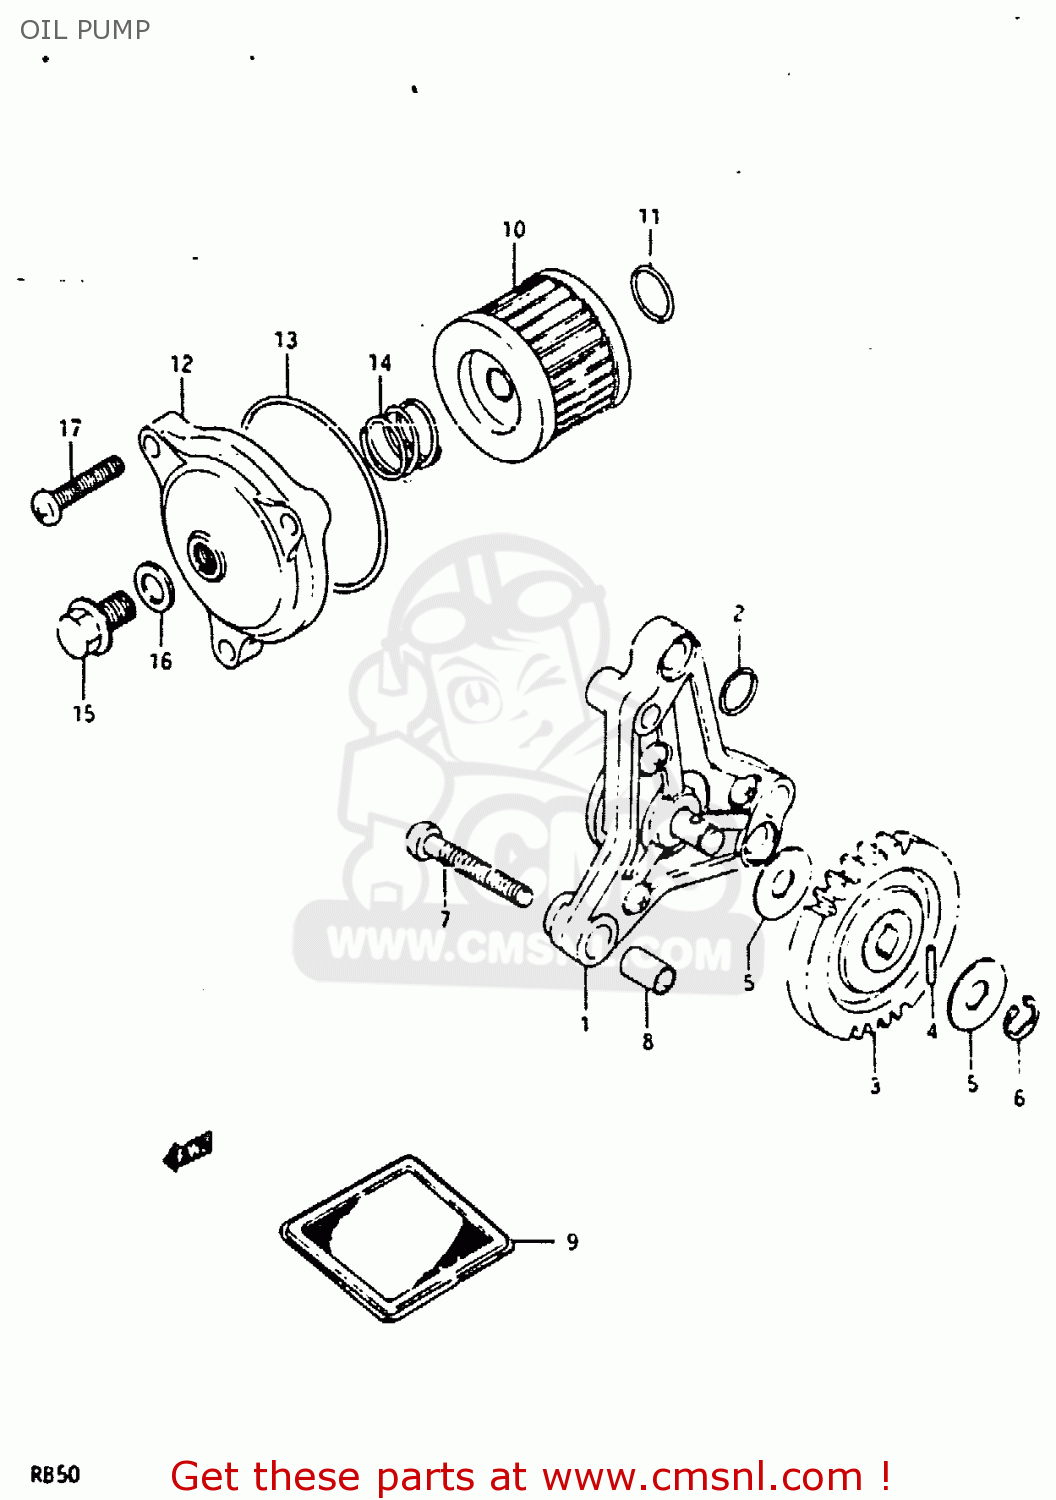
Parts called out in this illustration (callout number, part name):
1	PUMP ASSY,ENGINE OIL
2	O-RING
3	GEAR,OIL PUMP DRIVEN (N
4	PIN(2.5X11.8)
5	WASHER
6	E RING 6MM
7	SCREW
8	PIN
9	STRAINER,ENGINE OIL
10	FILTER ASSY,ENGINE OIL
11	O RING(D:1.9,ID:13)
12	CAP,OIL FILTER
13	O RING(D:2.4,ID:52.6)
14	SPRING
15	BOLT
16	GASKET(8.2X14X1).6 (NAS)
17	SCREW
